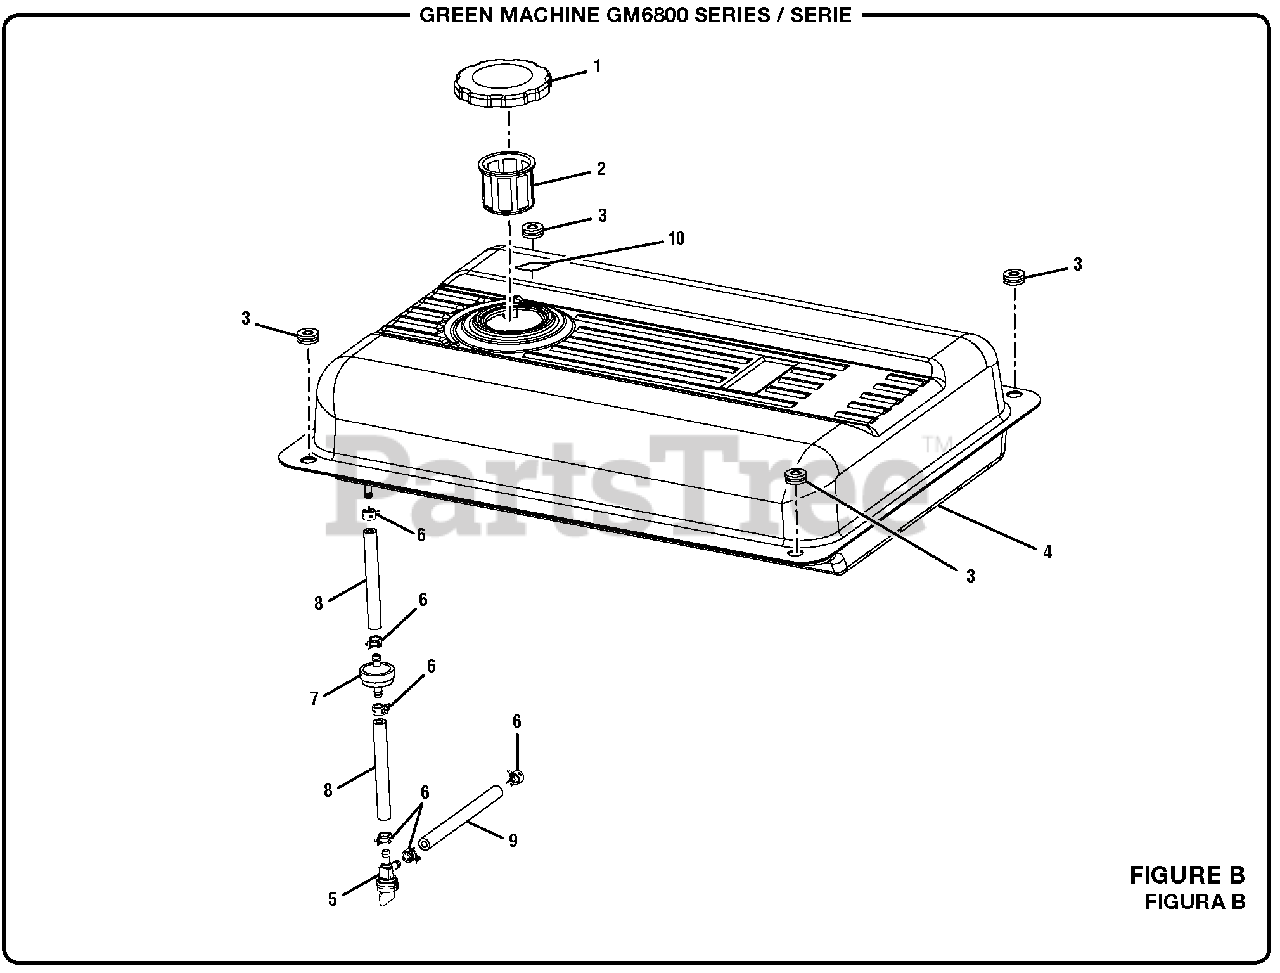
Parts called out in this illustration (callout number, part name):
1	Fuel Tank Cap
2	Fuel Tank Screen
3	Bushing w/Insert
4	Fuel Tank
5	Fuel Valve
6	Fuel Line Clamp (1/2 in.)
7	Fuel Line Filter
8	Fuel Line (1/4 in.)
9	Fuel Hose (5 mm)
10	E85 Lable
